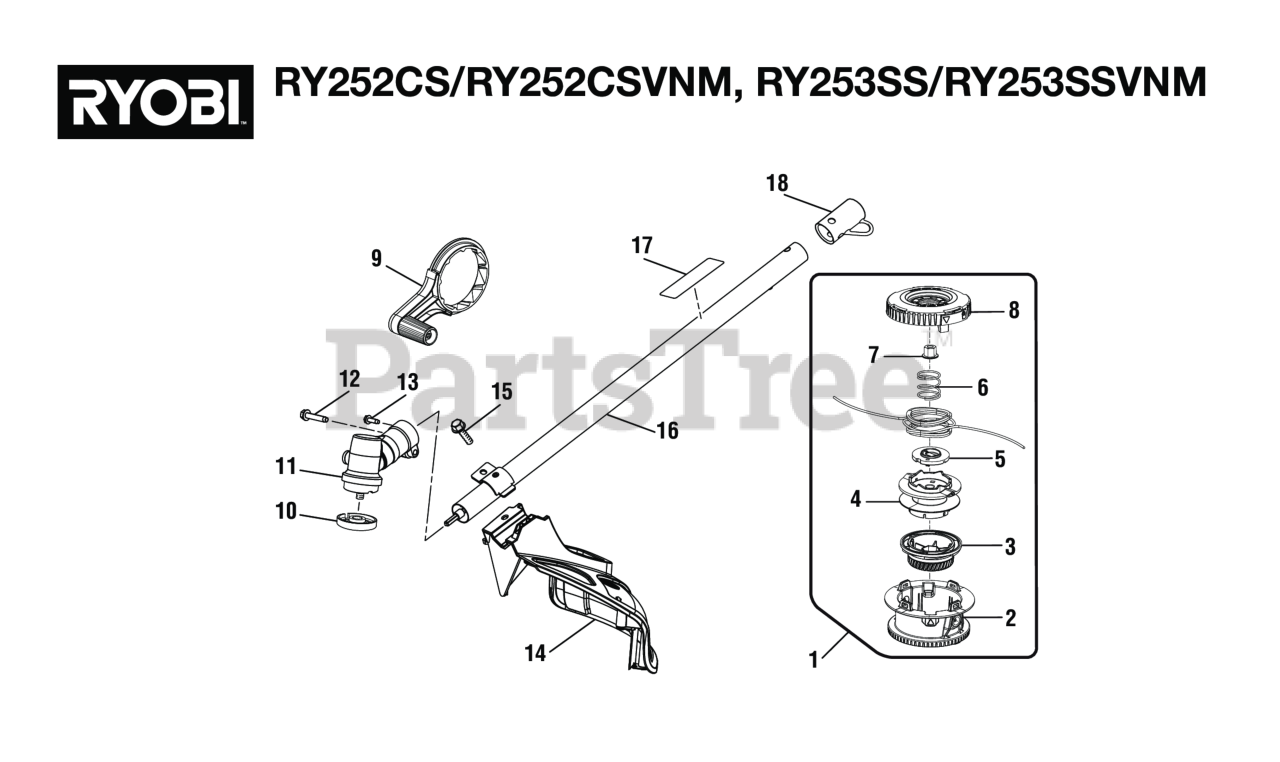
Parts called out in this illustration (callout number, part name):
1	Trimmer Head Assembly (.095) (Inc. Key Nos. 19-25)
2	Bump Head
3	Bump Knob (Green)
4	Spool Assembly
5	String Guide
6	Compression Spring
7	Hex Nut (M8, Left Hand Threads)
8	Locking Assembly
9	Crank Handle
10	FLANGED WASHER
11	Gear Case Assembly
12	Screw (1/4-20 x 1-1/4 in., Hex Washer Hd. S.T.)
13	Screw w/Washer (10-24 x 5/8 in., Hex Hd. T.F.)
14	Grass Deflector Assembly
15	SCREW (#1/4-20 X 1-1/4 in. HEX WASHER HD.)
16	Straight Shaft Assembly (Inc. Key Nos. 17-18)
17	Warning Icon Label
18	Storage Hanger Cap
